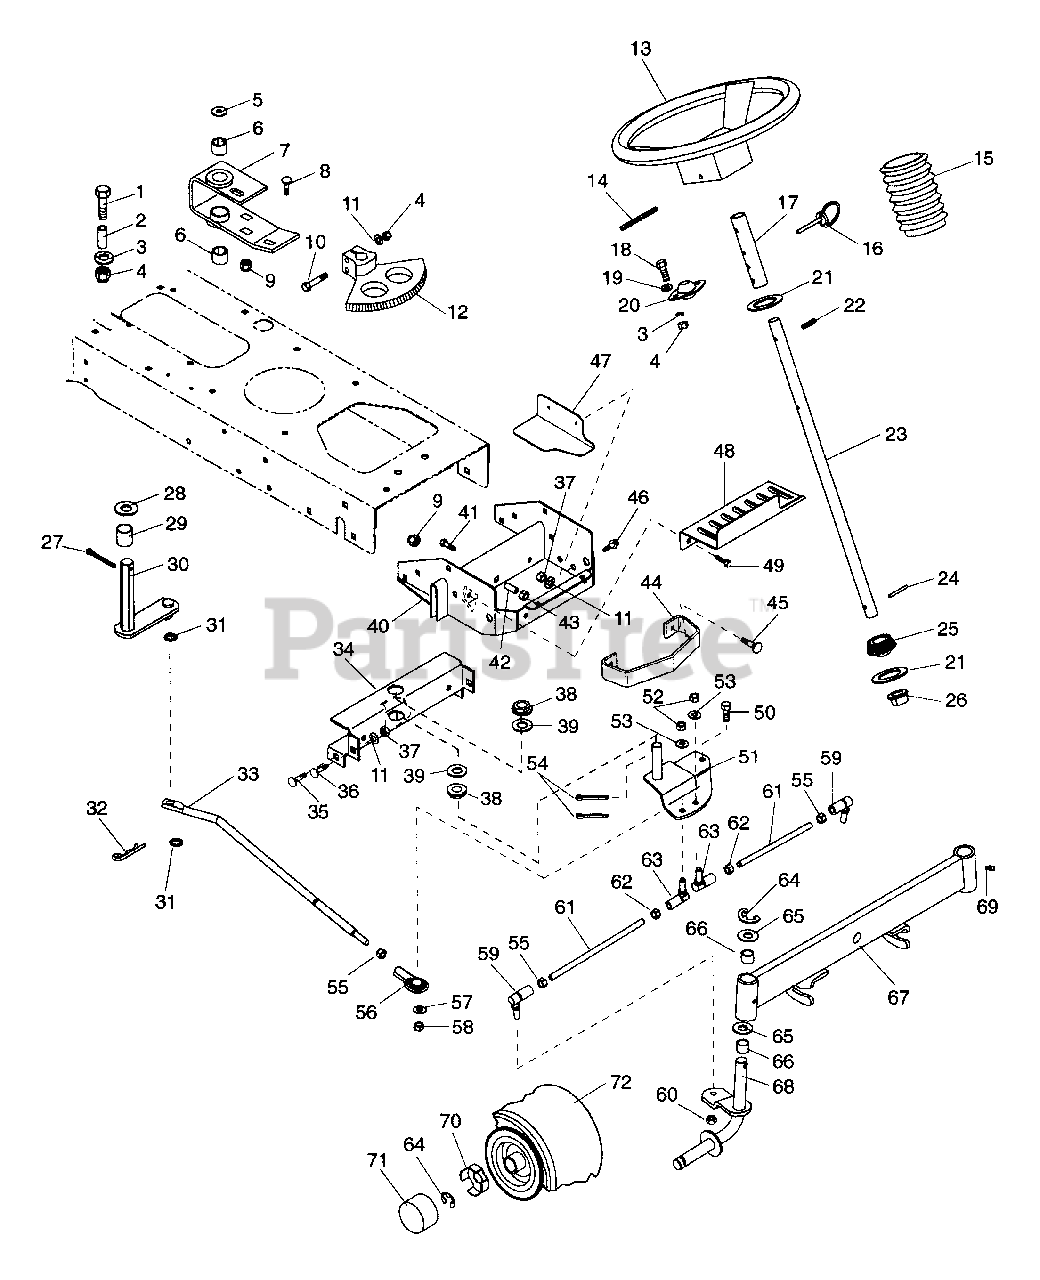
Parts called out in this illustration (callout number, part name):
1	BLT-HEX .31-18X1.50 PL GR2
2	SPACER .344X.500X.875
3	WSHR-LK .312X.097 PL HVY
4	NUT-HEX .312-18
5	WSHR-FL-STL .880X1.250X.062
6	BSHG-SLV .750X1.000X.750 HX SB
7	STEERING BRACKET
8	BLT-RDHDSQNK .375-16X.75 GR5PL
9	NUT-LK-CTR .375-16 GR A PL
10	BLT-HEX .31-18X1.75 PL GR2
11	WSHR-LK .312X.097 PL HVY
12	STEERING BEVEL GEAR
13	STEERING WHEEL 13"
14	PIN-ROLL .250X1.75
16	PIN-DET W/RING .25X1.00
17	TUBE .754 X .999 X 5.00
18	BLT-HEX .31-18X.75 PL GR5
19	WSHR-FL-STL.312X.734X.065PL
20	BRG-FLG .751X2 HOLESX.81
21	WSHR-FL-STL .754X1.125X.062 PL
22	PIN-ROLL .188X1.13
23	STEERING COLUMN
24	PIN .249X1.125 DRIV-LOK SP
25	PINION GEAR-STEERING
26	BSHG-FLG .750X1.093X.625X1.375
27	PIN-COTR .18X1.25 PL
28	WSHR-FL-STL .875X1.250X.075
29	SPACER .900X1.017X1.090
30	ARM & SHAFT
31	WSHR-FL-STL .520X.827X.062 YZ
32	PIN-HAIR INT .08X.38X1.42 YWZC
33	DRAG LINK
34	STEERING PIVOT CHANNEL
35	BLT-RDHDSQSHNK .38-16X1.00 PL
36	BLT-RDHDSQNK .38-16X.75 SHT PL
37	NUT-HEX .375-16
38	FLANGE BUSHING
39	WSHR-FL-STL.656X1.312X.095 PL
40	FRONT AXLE SUPPORT
41	BLT-HEX .50-13X1.50 PL GR5
42	SPACER .531X.748X.524
43	NUT-LK-CROWN .50-13 GR C PL
44	FRONT BUMPER
45	BLT-RDHDSQNK .38-16X.62 GR5 PL
46	SCR-TAP 12-24X.50 HWH PL TR
47	DEFLECTOR PLATE
48	BAFFLE- HEAT (ENG.COOLING AIR)
49	BLT-HEX .38-16X.75 PL GR5
50	BLT-HEX .38-16X1.25 PL GR5
51	STEERING PIVOT
52	NUT-LK-CTR .375-24
53	WSHR-FL-STL .390X.750X.125 PL
54	PIN-COTR .12 X 1.25 PL
55	NUT .375-24 PL
56	ROD END, .38 RH
57	WSHR-FL-STL .382X.812X.062
58	NUT-LK TOP .375-16 GR C YWZC
59	BALL JOINT-RH
60	NUT-LK .375-24 PL
61	TIE ROD
62	NUT L.H. THD .375-24 PL
63	BALL JOINT-LH
64	RG-RTNG-EXT .750X.050
65	WSHR-FL-STL .755X1.375X.093
66	BSHG-SLV .750X.814X .750 BRZ
67	FRONT AXLE
68	SPINDLE LH
68	SPINDLE RH
69	FTG-LUBE .25-28X.256 YWZC
70	SPINDLE CUP
71	HUB CAP
72	T/WHL ASSY 13X5.00-6
72	RIM
72	TIRE
72	T/WHL ASSY 15X6.00-6
72	BSHG .75 BORE
